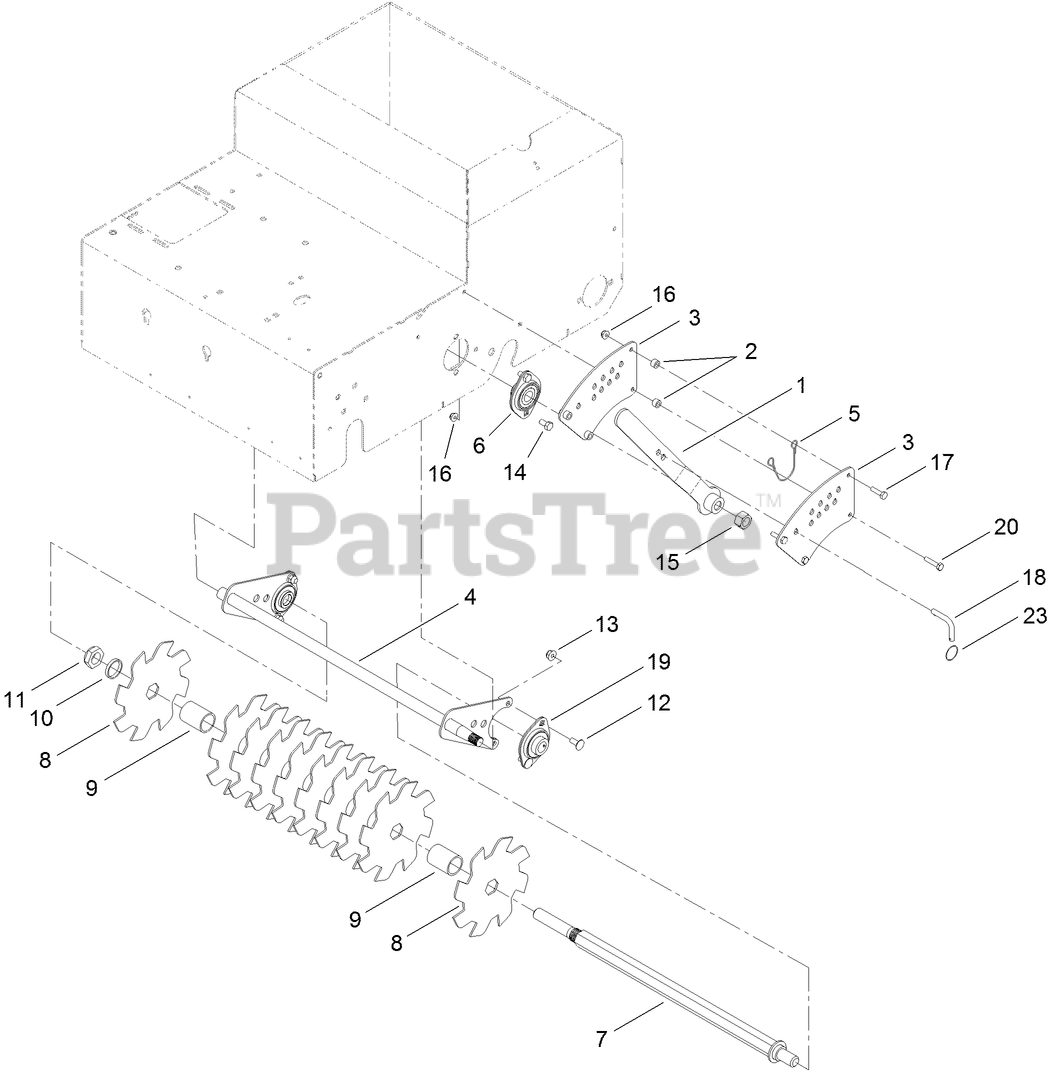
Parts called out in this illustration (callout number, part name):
1	HEIGHT CONTROL ASM
2	SPACER
3	BRACKET-HEIGHT
4	PIVOT-HEIGHT
5	LANYARD
6	BEARING
7	SHAFT ASM
8	BLADE-CUTTING, SEEDER
9	SPACER
10	SPACER-RETAINING
11	NUT-LOCK, NI
12	SCREW-CARR
13	NUT-HF, NI
14	SCREW-HH
15	NUT-BLADE
16	NUT-HF
17	SCREW-HH
18	PIN-KEYED
19	BEARING
20	SCREW-HH
23	RING-KEY
